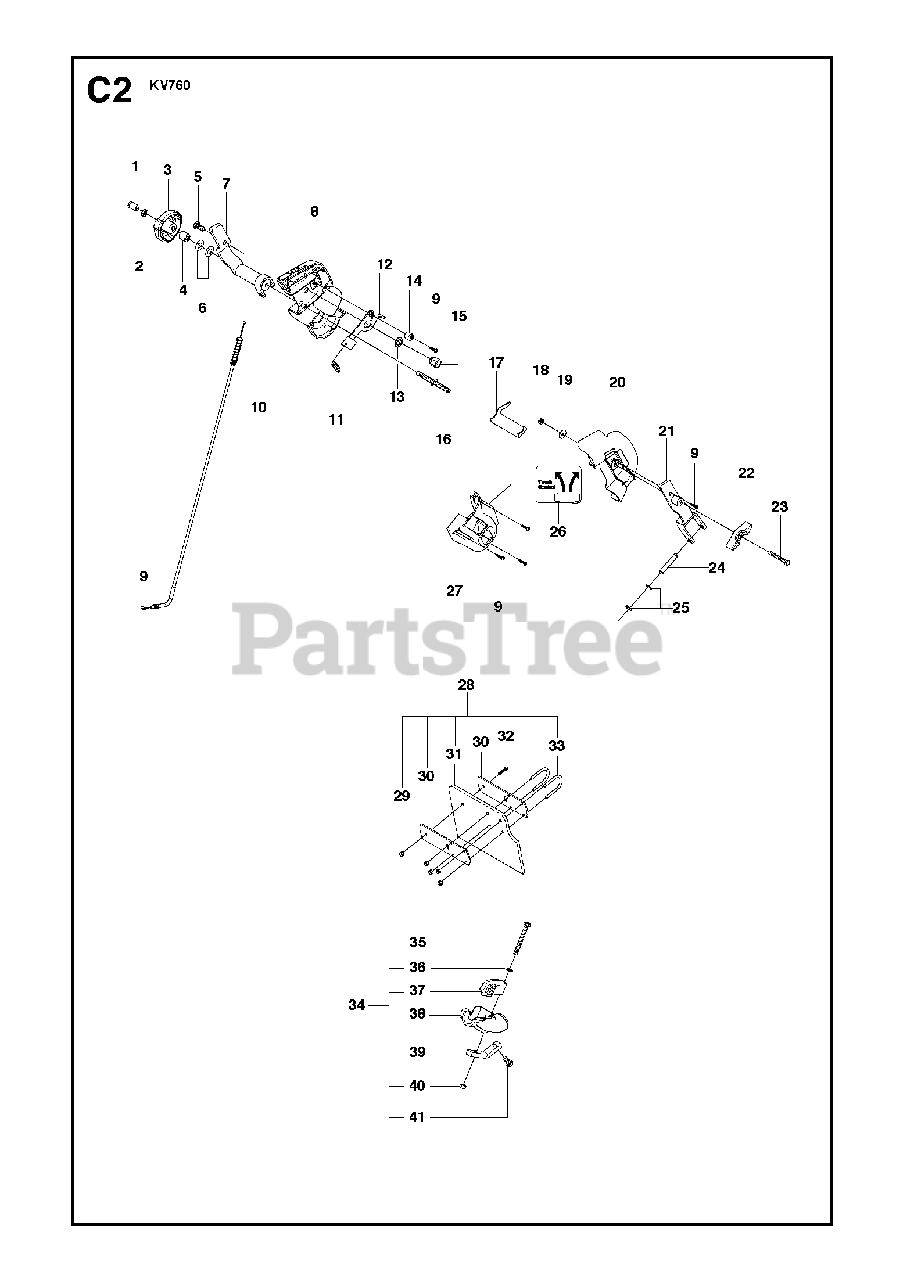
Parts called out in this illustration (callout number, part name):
2	HEXAGON NUT
3	TURNING KNOB
4	SPACING SLEEVE
18	HEXAGON LOCKING NUT
29	HEXAGON LOCKING NUT
36	WASHER
37	TURNING KNOB
40	HEXAGON LOCKING NUT
